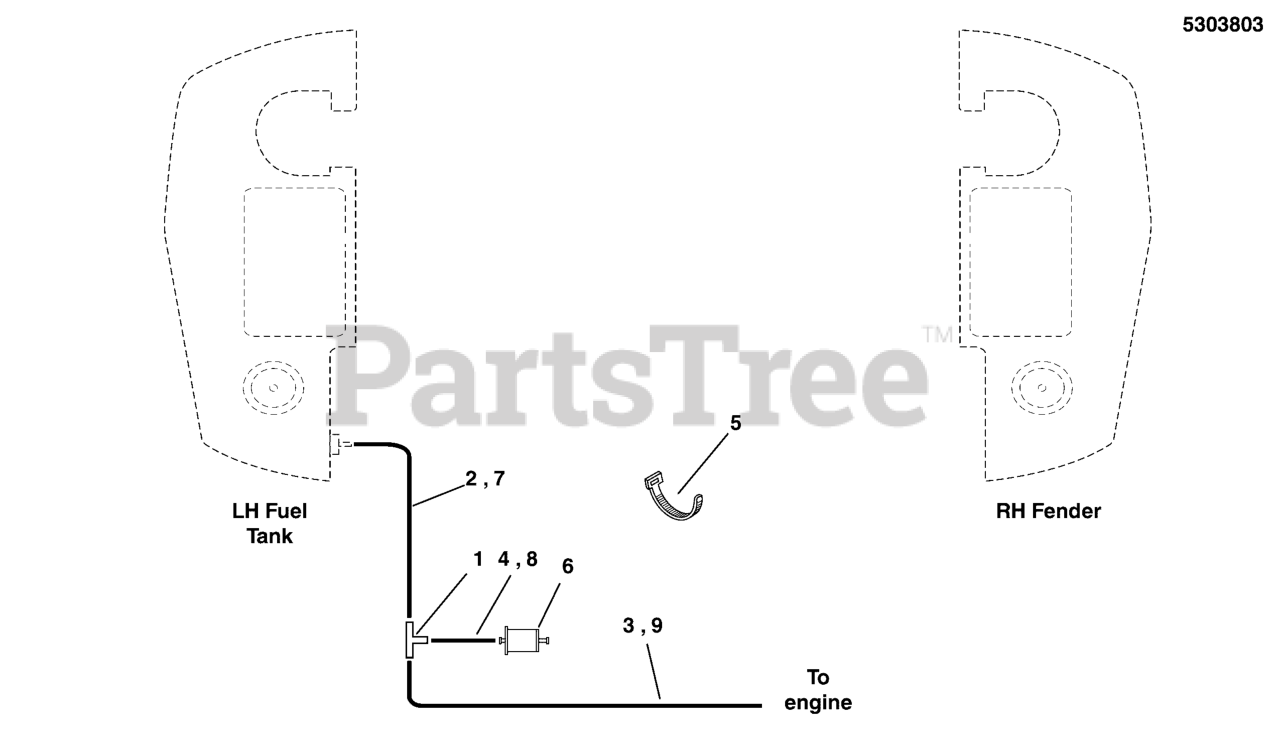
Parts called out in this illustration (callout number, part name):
1	FITTING, 3/16" TEE, BARB TYPE, HDPE
2	HOSE, VAPOR, 5MM ID, 24.00 LG
3	HOSE-VAPOR
4	HOSE, VAPOR, 5MM ID, 19.00 LG
5	TIE, SELF-LOCKING, 6"
6	FILTER, FUEL
7	HOSE, VAPOR, 5MM ID, 18.00 LG
8	HOSE, VAPOR, 5MM ID, 2.00 LG
9	HOSE, VAPOR, 5MM ID, 8.00 LG
